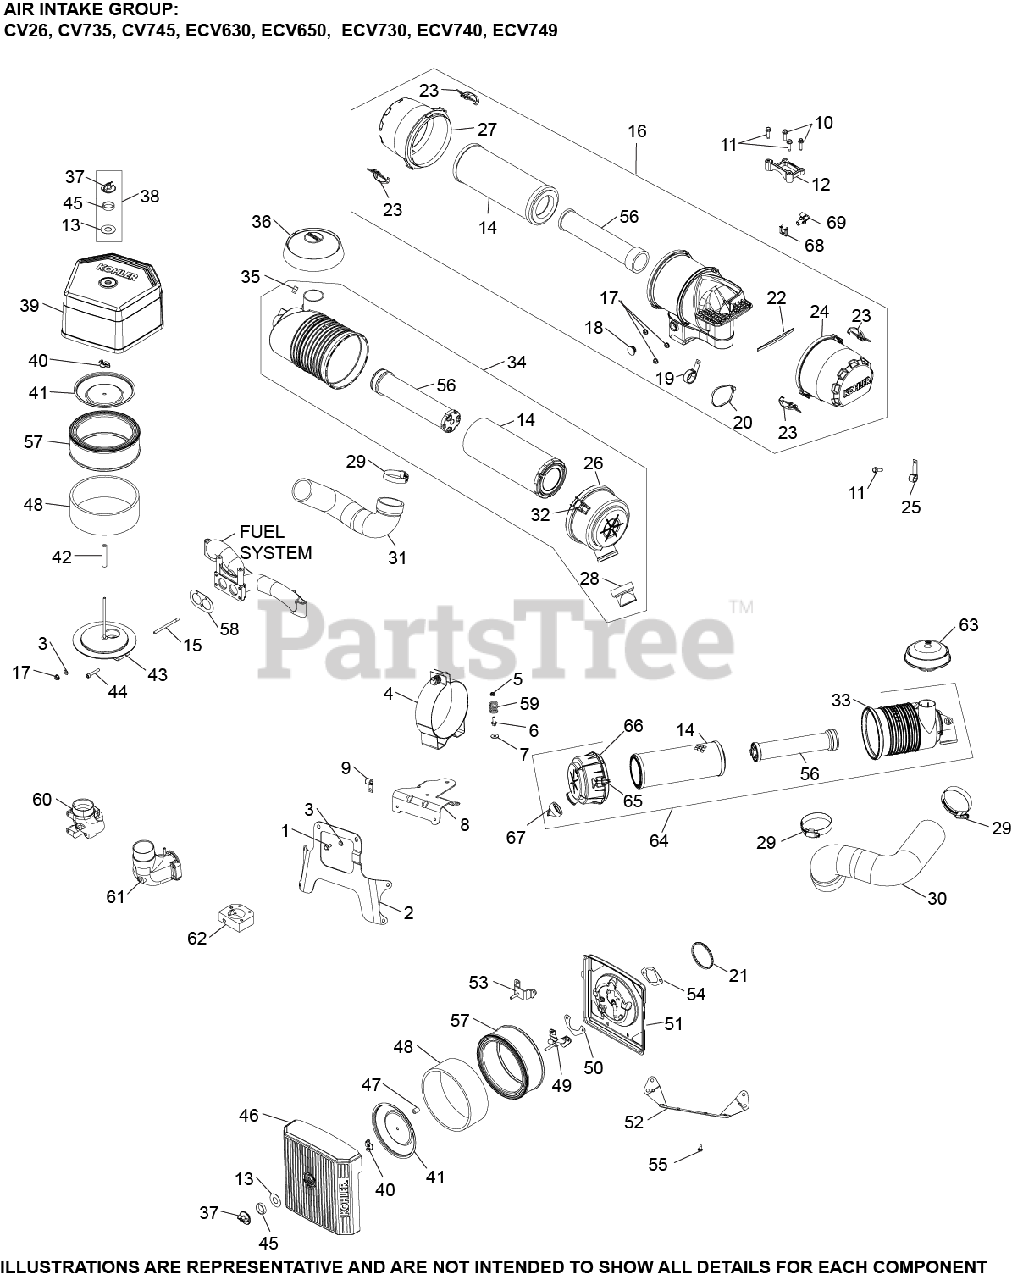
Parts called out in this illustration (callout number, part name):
11	SCREW, THREAD FORMING
12	BRACKET, A/C VERT HDAC (EFI)
14	ELEMENT, AIR FILTER - PRIMARY
16	KIT, AIR CLEANER
18	PLUG, HOLE
21	O-RING (HDAC SEAL-EFI)
22	DAMPER, FOAM INSERT
23	CLIP ASSEMBLY
24	COVER, RAIN CAP
25	CLIP, CABLE
27	COVER, AIR FILTER
56	ELEMENT, AIR FILTER - SAFETY
68	CLIP, BAFFLE MOUNTING
69	FITTING, CONNECTOR EVAP
